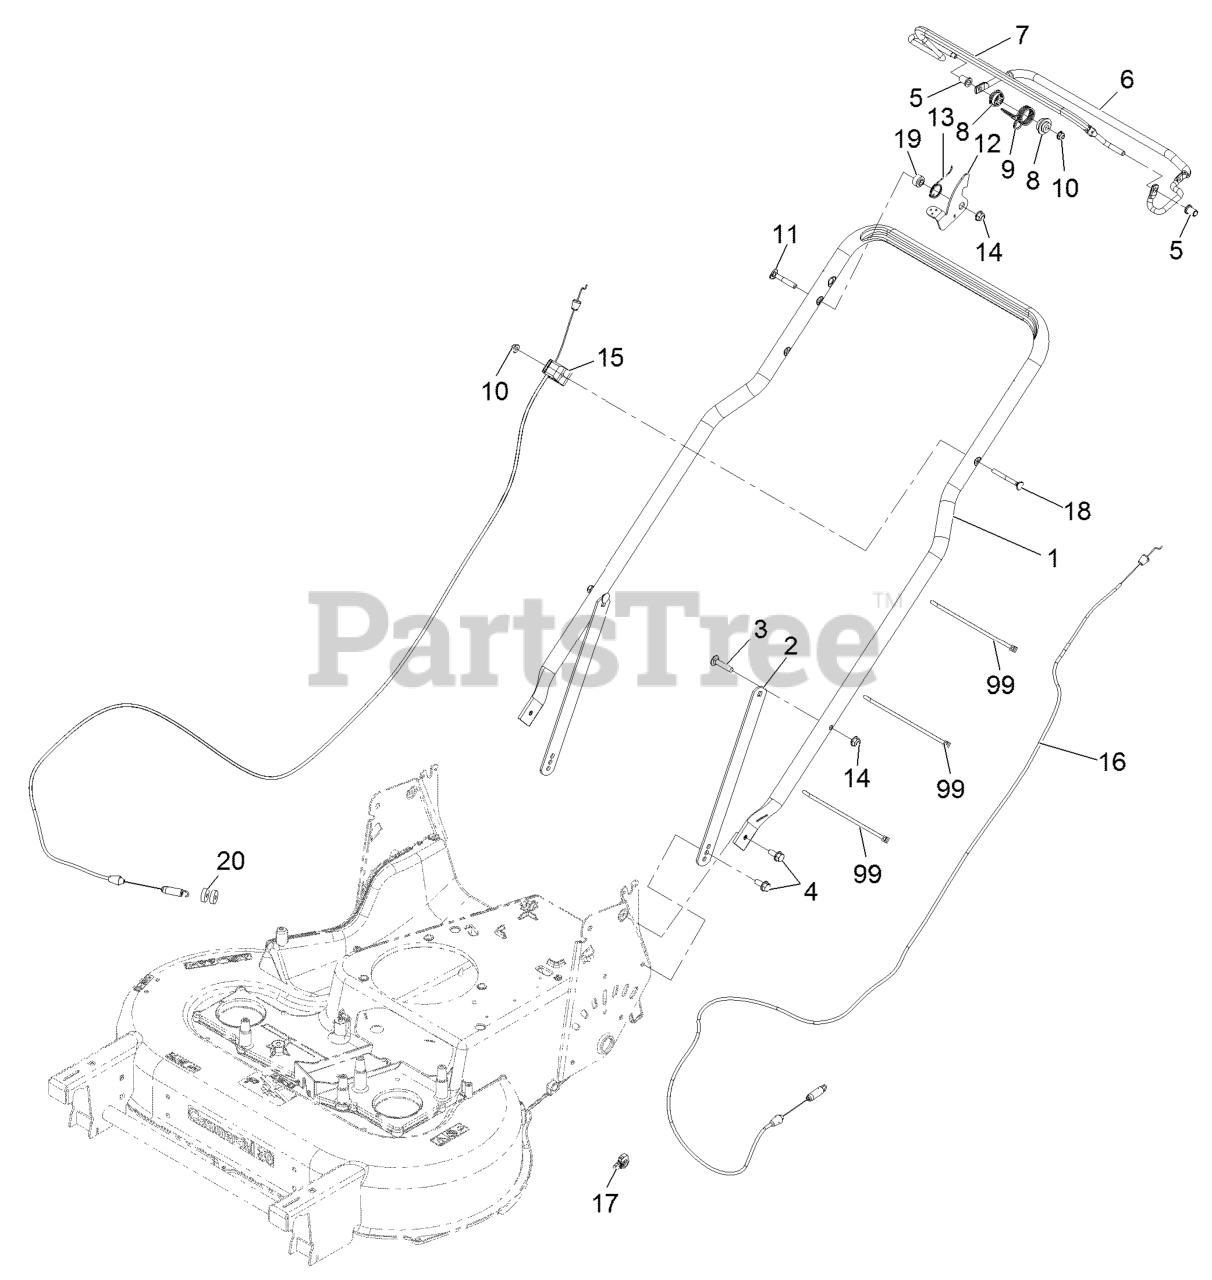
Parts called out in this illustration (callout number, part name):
2	SUPPORT-HANDLE
3	BOLT-CARR
4	SCREW-HHF
5	BUSHING-HANDLEBAR
6	BAIL-DRIVE COATED
8	BUSHING-SPRING, PIVOT
9	SPRING-RETURN, BBC
12	LEVER-BBC
13	SPRING-LEVER, BBC
14	NUT-HF, NI
16	CABLE-DRIVE, CROSSCUT
17	CLIP-CONDUIT
18	SCREW-HANDLE
19	BUSHING-STEPPED
99	TIE-CABLE
